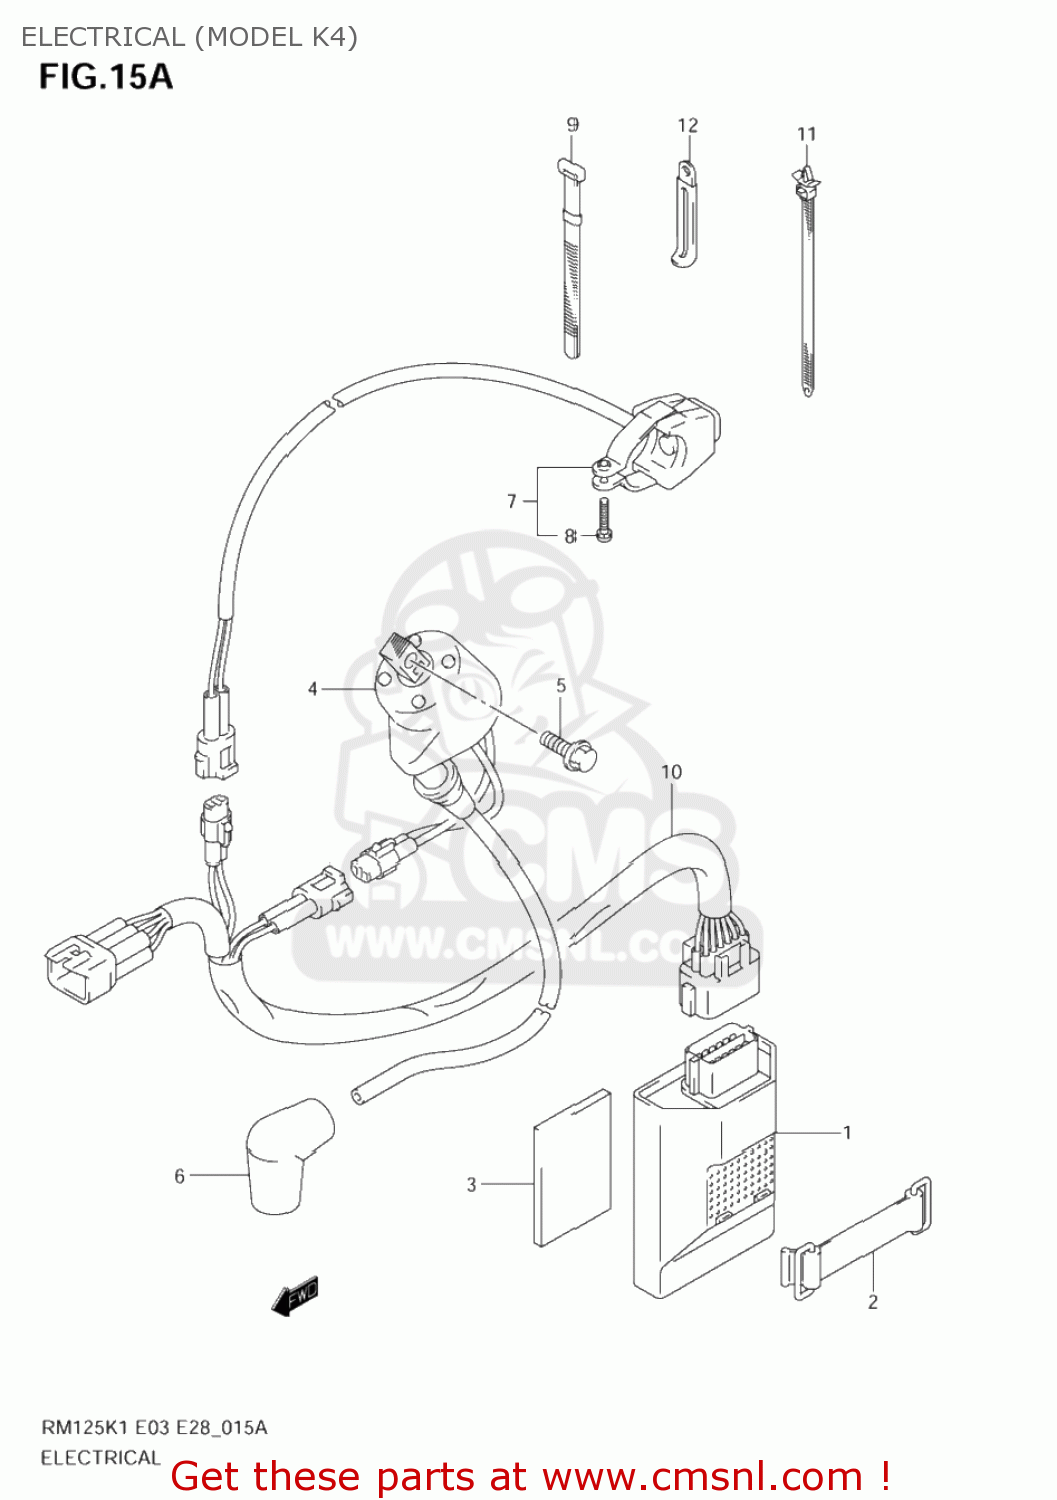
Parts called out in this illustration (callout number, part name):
1	CDI UNIT
2	BAND,CDI UNIT(L:80)
3	PROTECTOR(170X95X3.0)
4	COIL ASSY,IGNITION
5	BOLT(6X16)
6	CAP,SPARK PLUG
7	SWITCH ASSY,ENGINE STOP
8	SCREW
9	CLAMP(L:120)
10	HARNESS,WIRING
11	CLAMP(L:90)
12	CLAMP(L:45)
